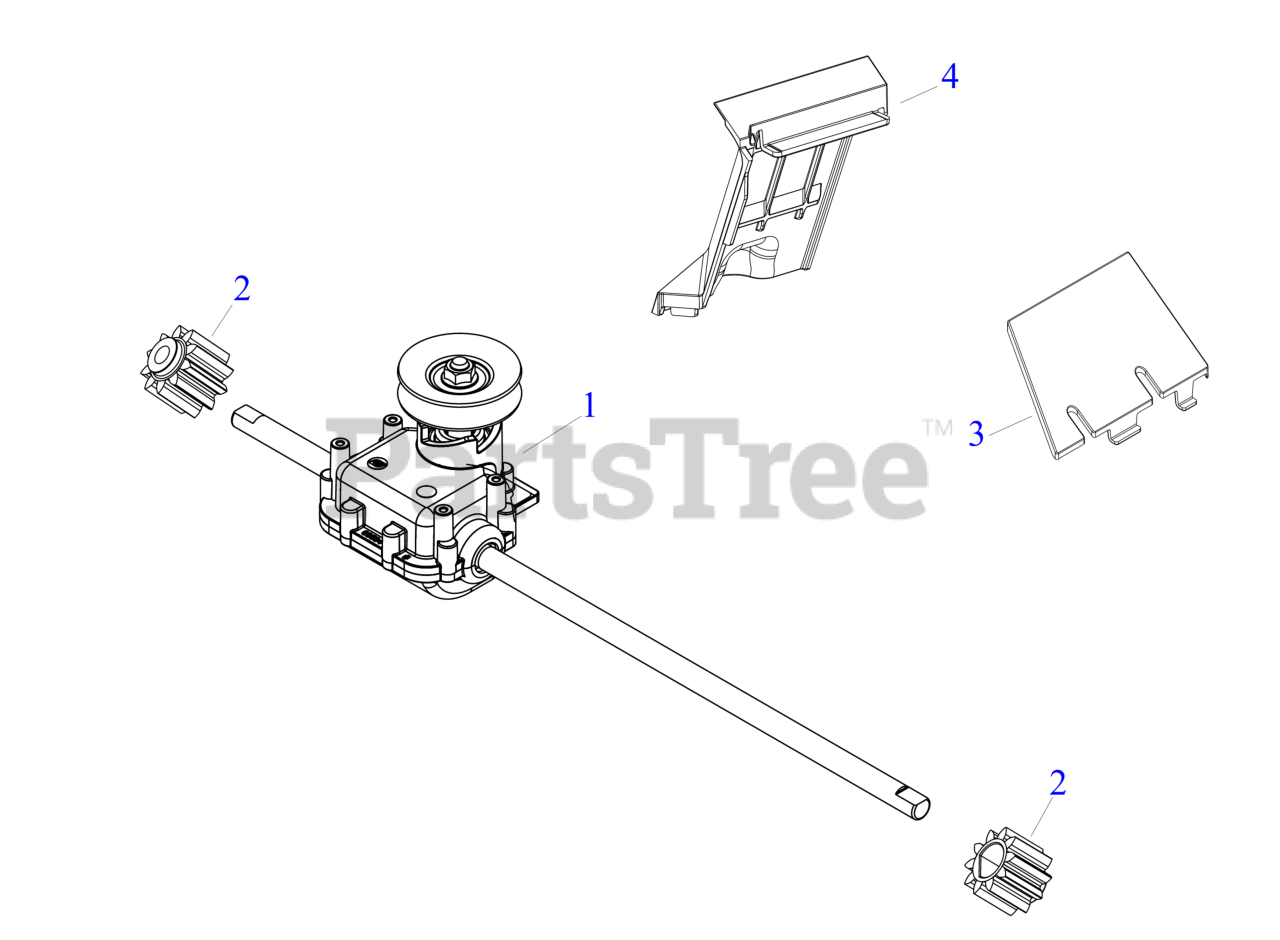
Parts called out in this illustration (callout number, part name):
1	TRANSMISSION
2	SPUR GEAR (10T)
3	TRANSMISSION COVER (REAR)
4	TRANSMISSION COVER (REAR)
